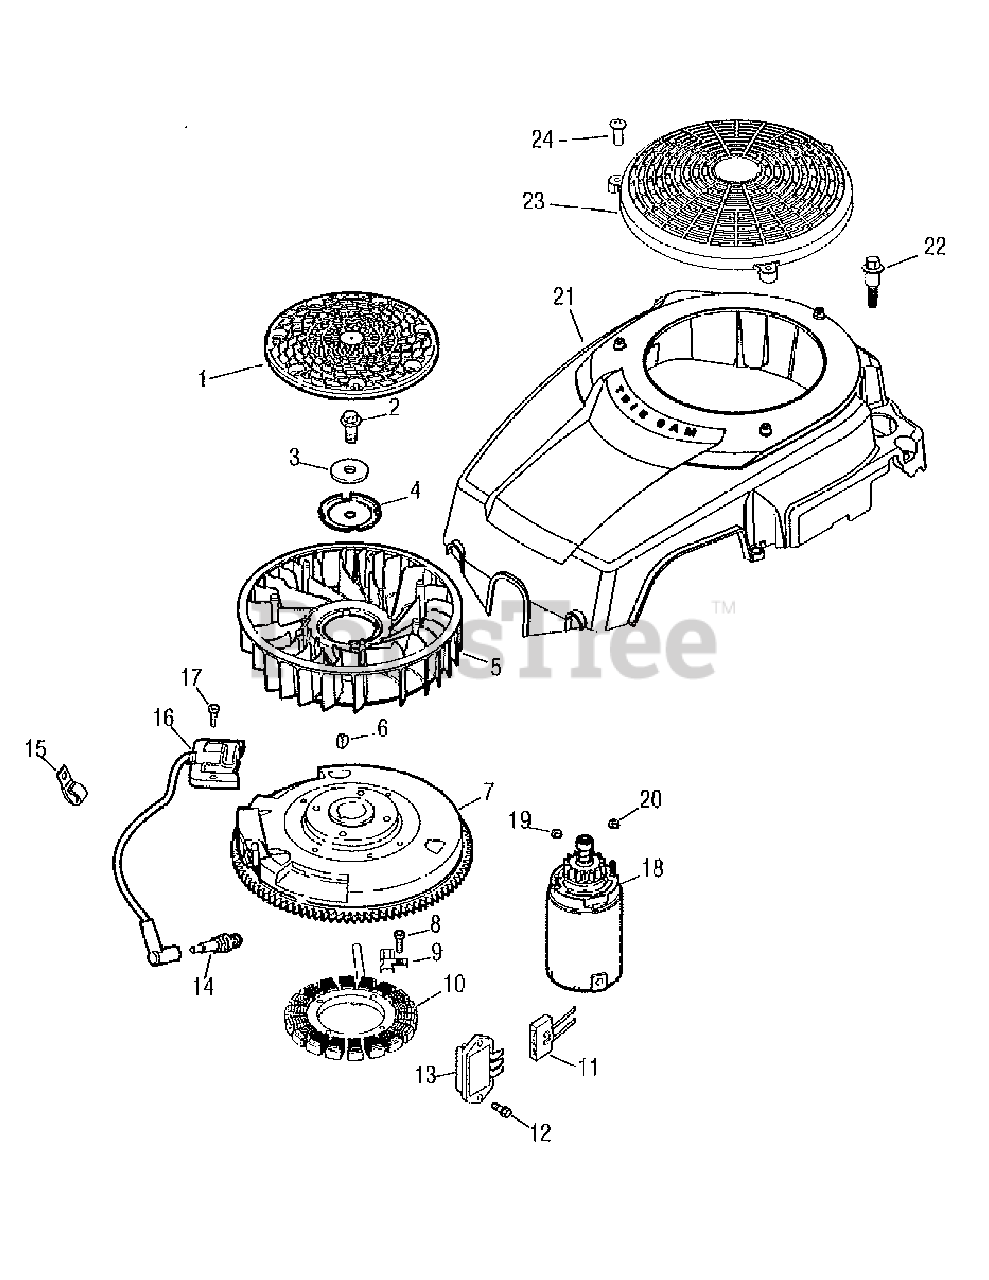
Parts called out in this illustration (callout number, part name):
1	Screen, Grass
2	Screw, Hex Flange, M10-1.5 x 46
3	Washer, Flat
4	Plate, Fan Mounting
6	Key, Woodruff
7	Flywheel
8	Screw, Hex Socket
10	Kit, Stator
11	Connector, Body (3 Contact)
12	Screw, Hex Flange
13	Rectifi er-Regulator
14	Plug, Spark
15	Clip, Cable
16	Module,Iignition
17	Screw, Hex Socket
18	Starter Ass’y, Inertia Drive
19	Nut, Hex Serrated Flange
20	Nut, Hex Flange 1/4-20
21	Housing, Blower
22	Screw, Shoulder M5-0.8 x 36
24	Screw, Tapping
